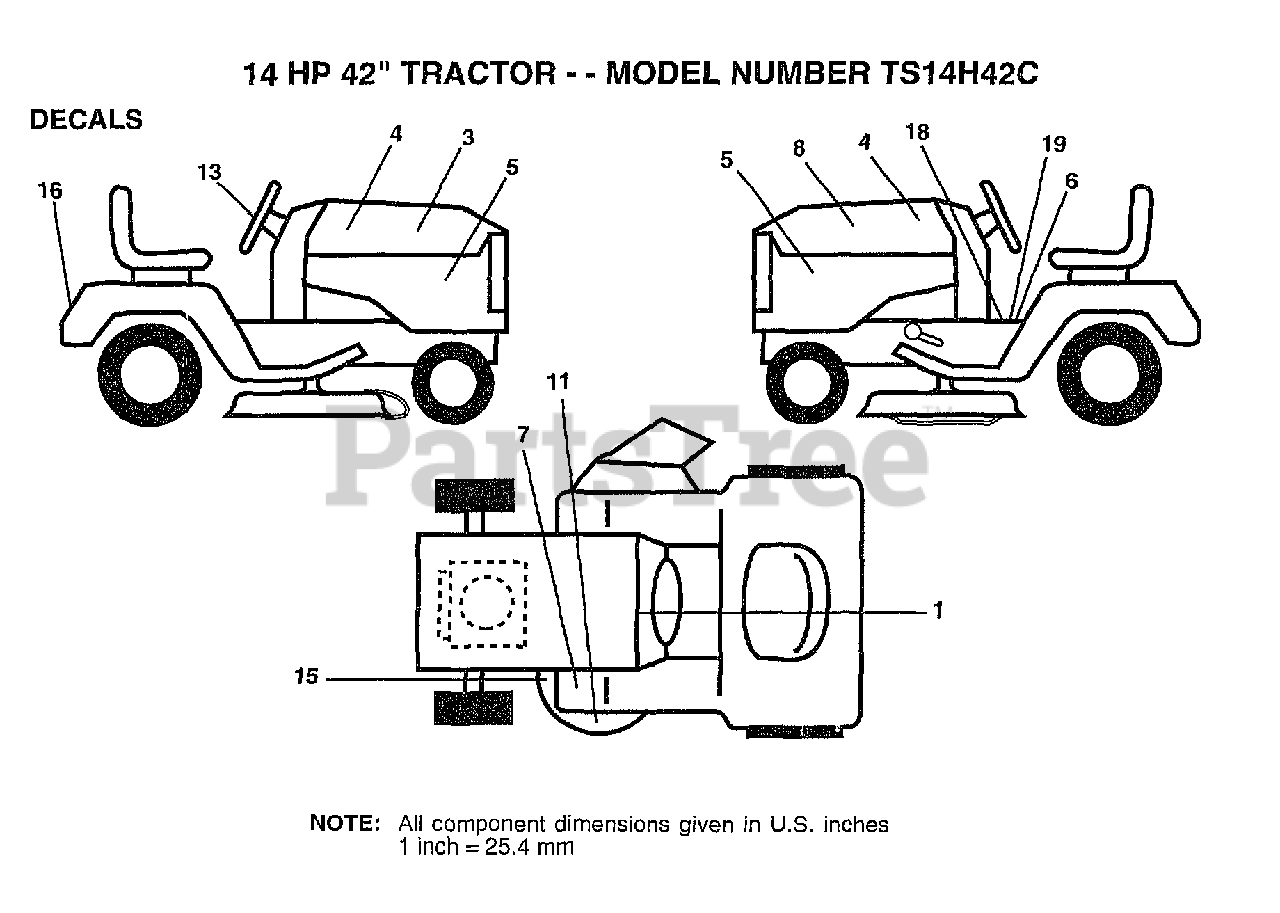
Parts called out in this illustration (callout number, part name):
1	DECAL.DASH.INST.
3	DECAL.HD.RH.14/42
4	NAMEPLATE.HUSK.LG
5	DECAL.PNL.SIDE.14
6	DECAL
8	DECAL.HD.LH.14/42
13	DECAL.INS.STG.WHL
15	DECAL.V.BELT
16	DECAL.FEND.HUSK
18	DECAL SADLE HYDRO
19	DECAL BRAK PARK
